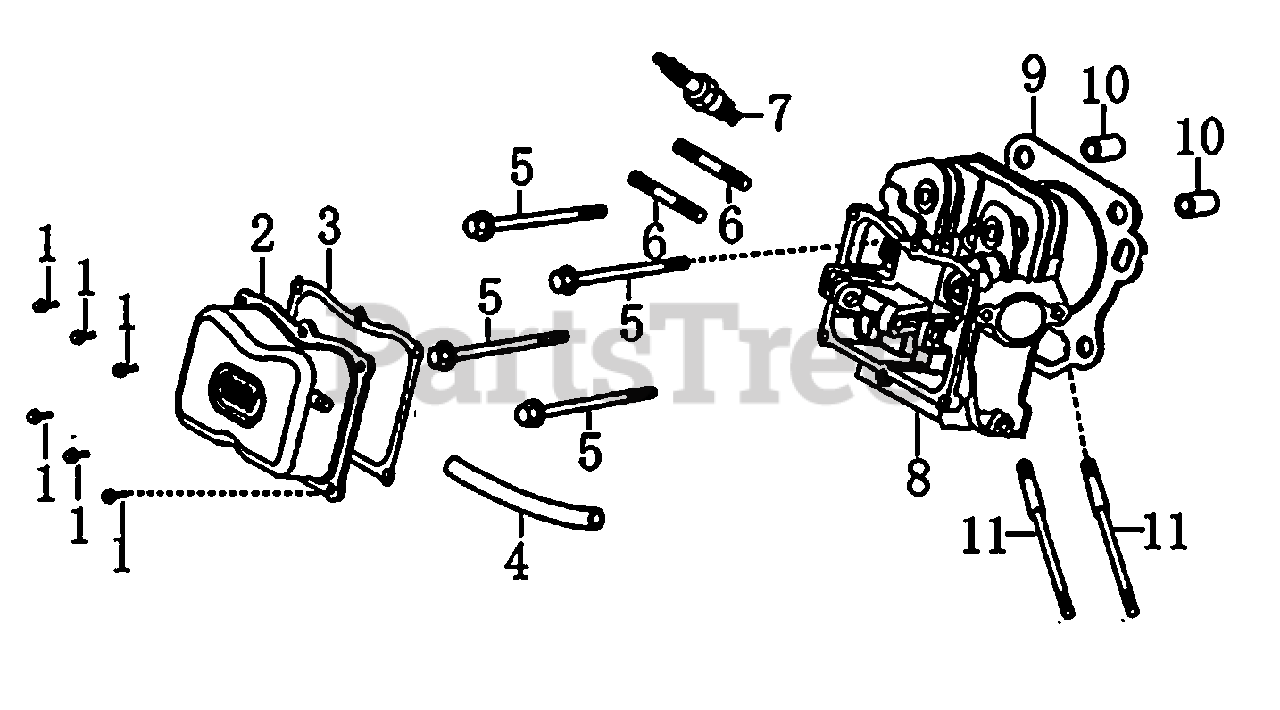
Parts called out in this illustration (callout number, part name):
1	BOLT, FLANGE
2	COVER, VALVE
3	GASKET, VALVE COVER
4	TUBE, BREATHER
5	BOLT, FLANGE, 10x80
6	BOLT, STUD, EXHAUST
7	SPARK PLUG
8	HEAD, CYLINDER
9	GASKET, CYLINDER HEAD
10	PIN, DOWEL
11	BOLT, STUD, INTAKE
